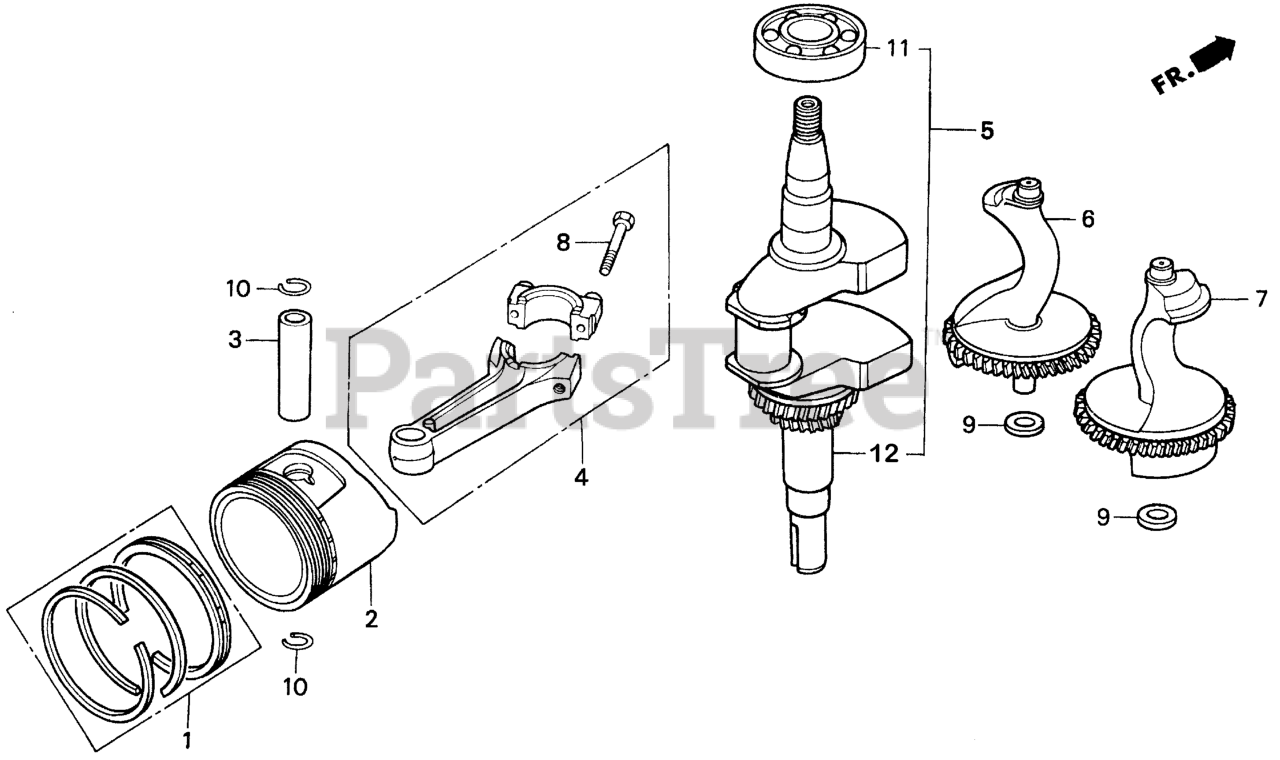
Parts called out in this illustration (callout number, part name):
1	RING SET, PISTON (STD)
1	RING SET, PISTON (OS 0.25)
1	RING SET, PISTON (OS 0.50)
1	RING SET, PISTON (0.75)
1	RING SET, PISTON (0.75) (TEIKOKU)
2	PISTON (STD)
2	PISTON (OS 0.25)
2	PISTON (OS 0.50)
2	PISTON (0.75)
3	PIN, PISTON
4	ROD ASSY., CONNECTING (US 0.25)
4	ROD ASSY., CONNECTING (STD)
5	CRANKSHAFT
6	WEIGHT A, BALANCER
7	WEIGHT B, BALANCER
8	BOLT, CONNECTING ROD
9	WASHER, THRUST (14MM)
10	CLIP, PISTON PIN (20MM)
11	BEARING, RADIAL BALL (6207)
